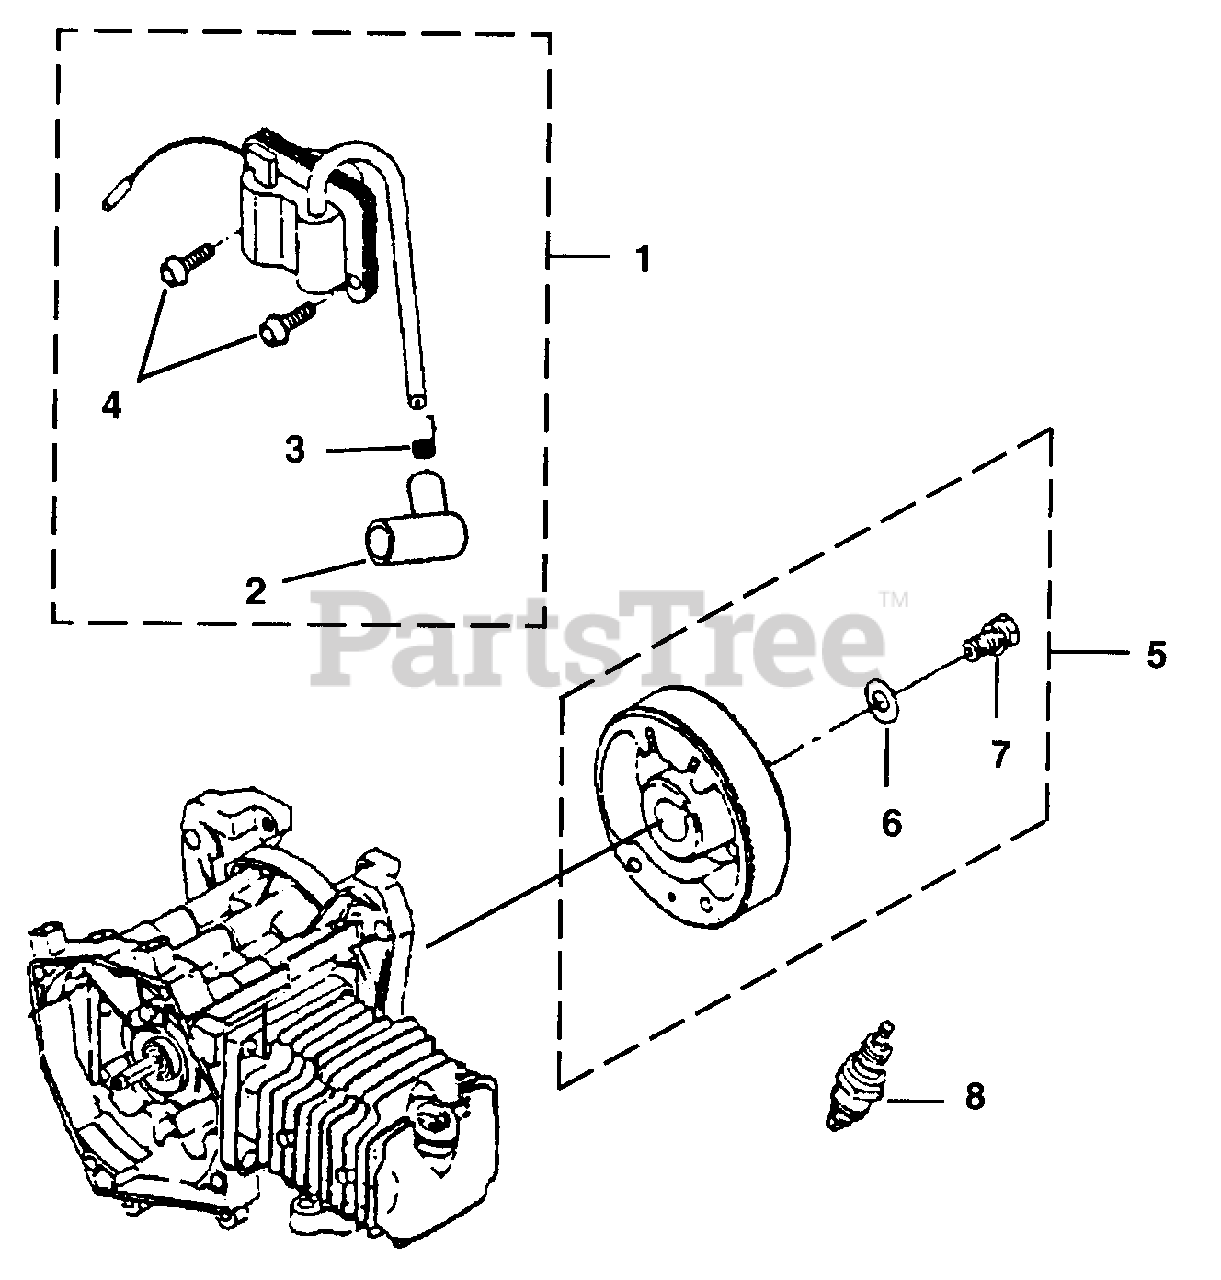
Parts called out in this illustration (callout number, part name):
1	IGNITION KIT
2	CAP-Plug
3	SPRING-Plug Cap
4	SCREW-Socket Hd (M5 x 22 W)
5	ROTOR ASSEMBLY
6	WASHER (M8)
7	BOLT ASSEMBLY (M8 x 16 SW)
8	SPARK PLUG
